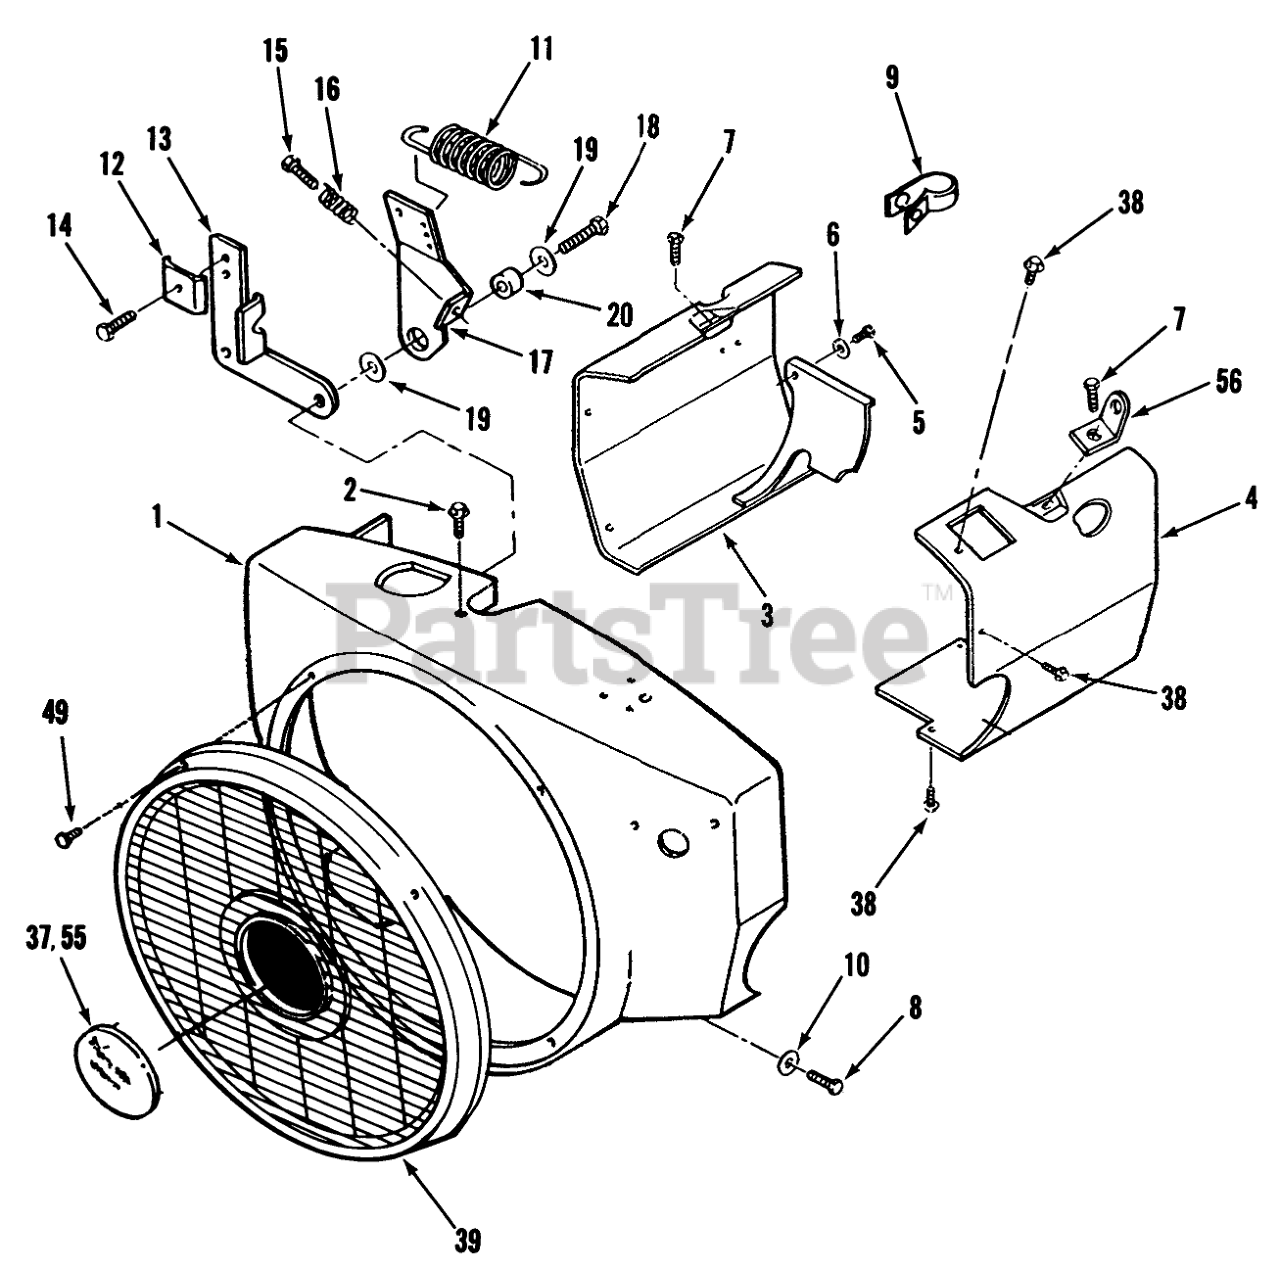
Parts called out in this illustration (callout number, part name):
1	Blower Housing
2	Bolt
3	CYLINDER AIR HSG L H
4	Cylinder Air Housing
5	Bolt
6	Screw
7	Bolt
8	Bolt
9	Clamp
10	Washer
11	Spring
12	Clip
13	Bracket
14	Bolt
15	Bolt
16	Spring
17	Arm
18	Bolt
19	Screw
20	Bushing
37	Plug
38	Bolt
39	GUARD
49	Screw 1/4-20 x 3/8
55	NAME-PLATE TORO LOGO
56	Bracket-Lifting
